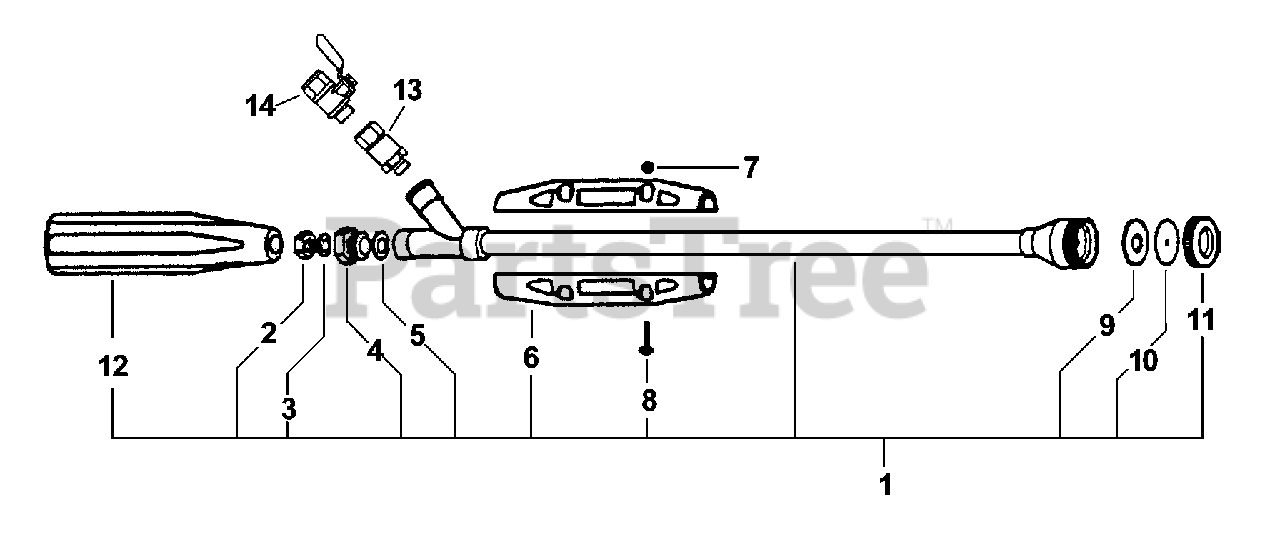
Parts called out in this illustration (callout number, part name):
1	ADJUSTABLE JET NOZZLE ASSY
3	GASKET
8	SCREW - 4X18
9	GASKET, NOZZLE
10	PLATE, NOZZLE
11	CAP, NOZZLE
13	COUPLING, SWIVEL
14	PETCOCK
